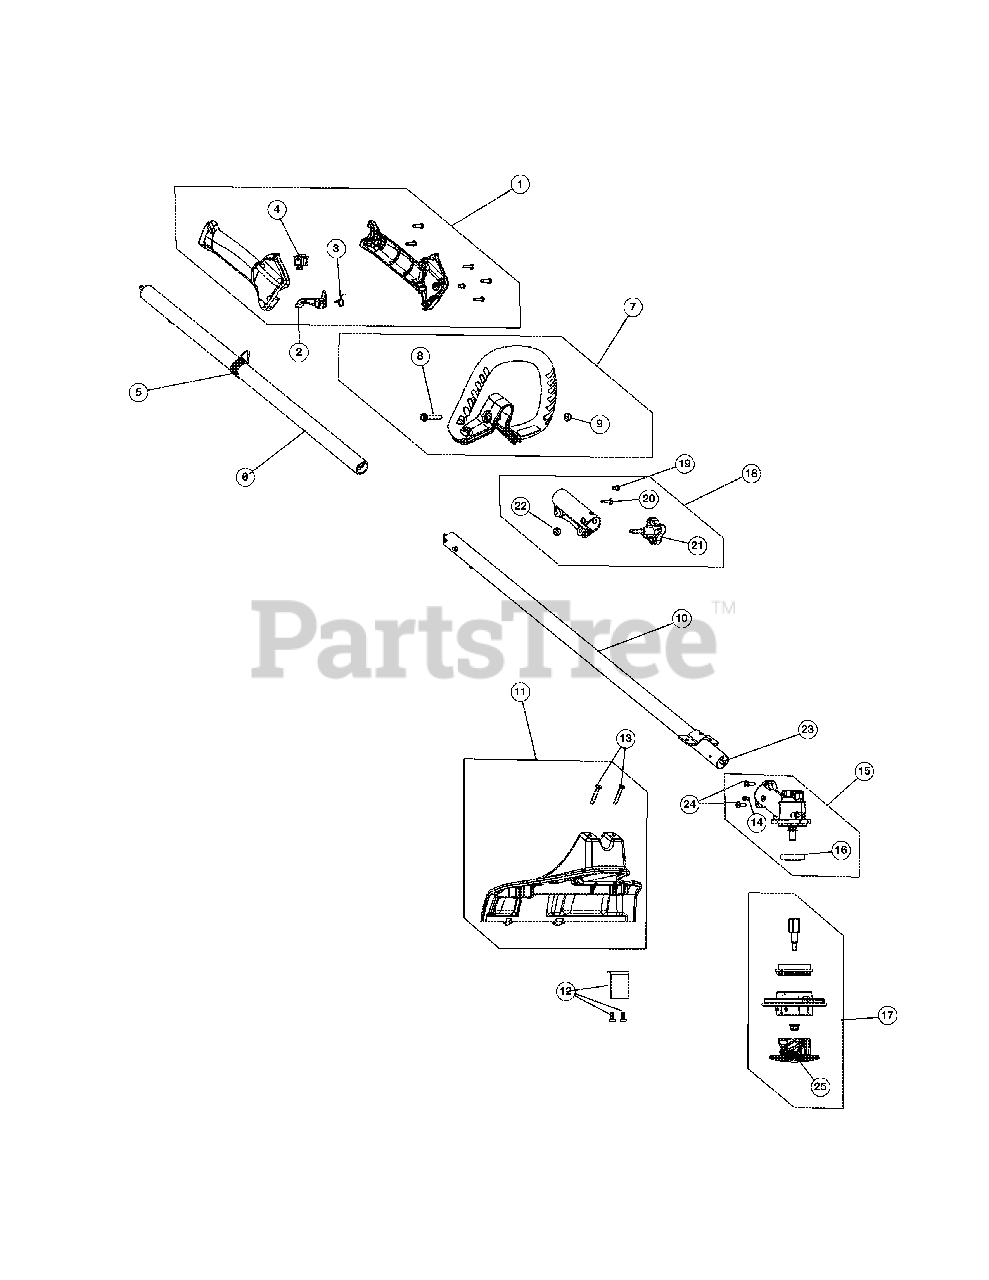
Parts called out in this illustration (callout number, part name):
1	Throttle Housing Assembly (Incl. Ref No. 2-4)
2	Throttle Trigger
5	Shoulder Strap Clip
6	Upper Drive Shaft Housing Assembly
7	Handle Assembly (Incl. Ref No. 8 & 9)
10	Lower Drive Shaft Housing Assembly
11	Shield Assembly (Incl. Ref No. 13)
12	Blade Assembly
14	Anti-Rotation Screw
15	Gear Box (Incl. Ref No. 14, 16 & 24)
16	Gear Box Spacer
17	Cutting Head Assembly (Incl. Ref No. 25)
18	Split Boom Coupler (Incl. Ref No. 19-22)
21	Adjustment Knob
22	Knob Retaining Nut
23	Lower Flexible Drive Shaft
24	Gear Box Screw
25	Cutting Head Cap
